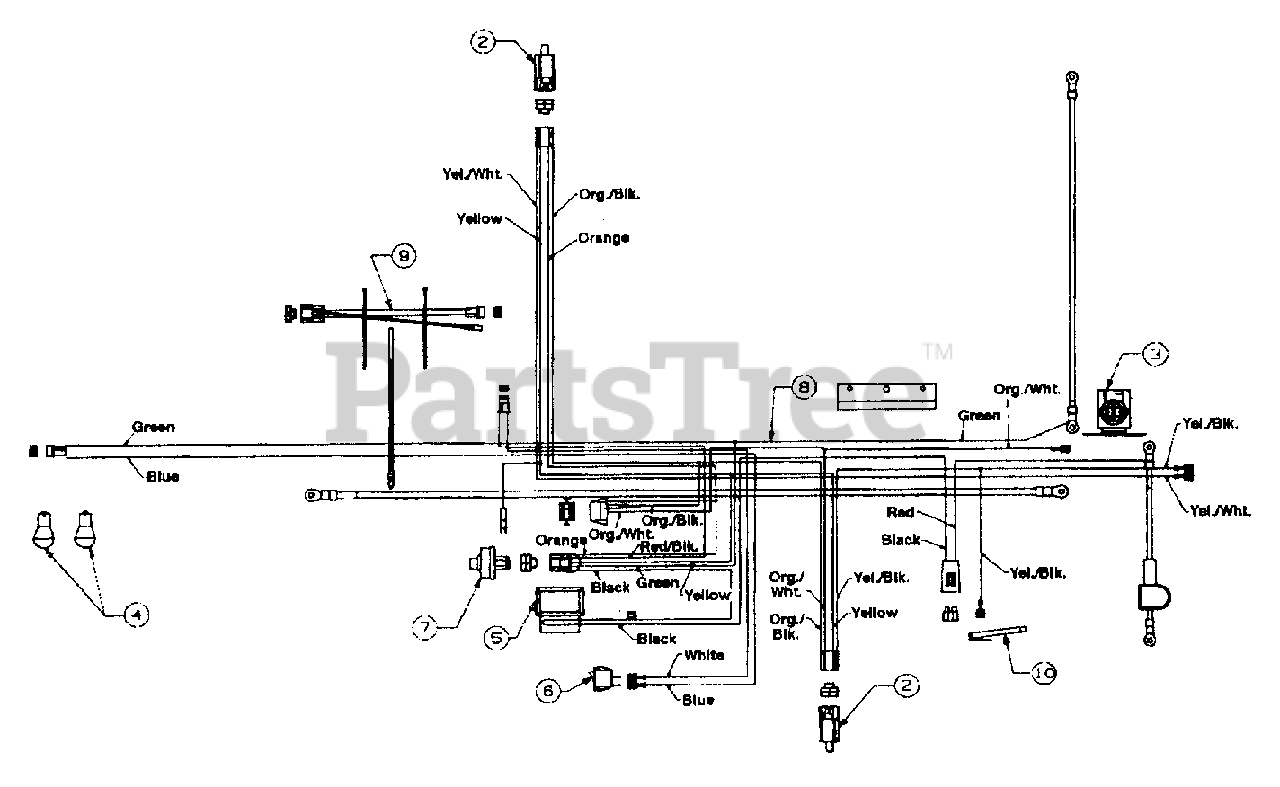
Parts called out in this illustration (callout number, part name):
2	Safety Switch
3	Solenoid
4	Bulb (Headlight)
5	Ammeter
6	Light Switch
7	Ignition Switch
8	Wire Harness
9	Wire Harness Adapter
10	Wire Harness (Monitor)
